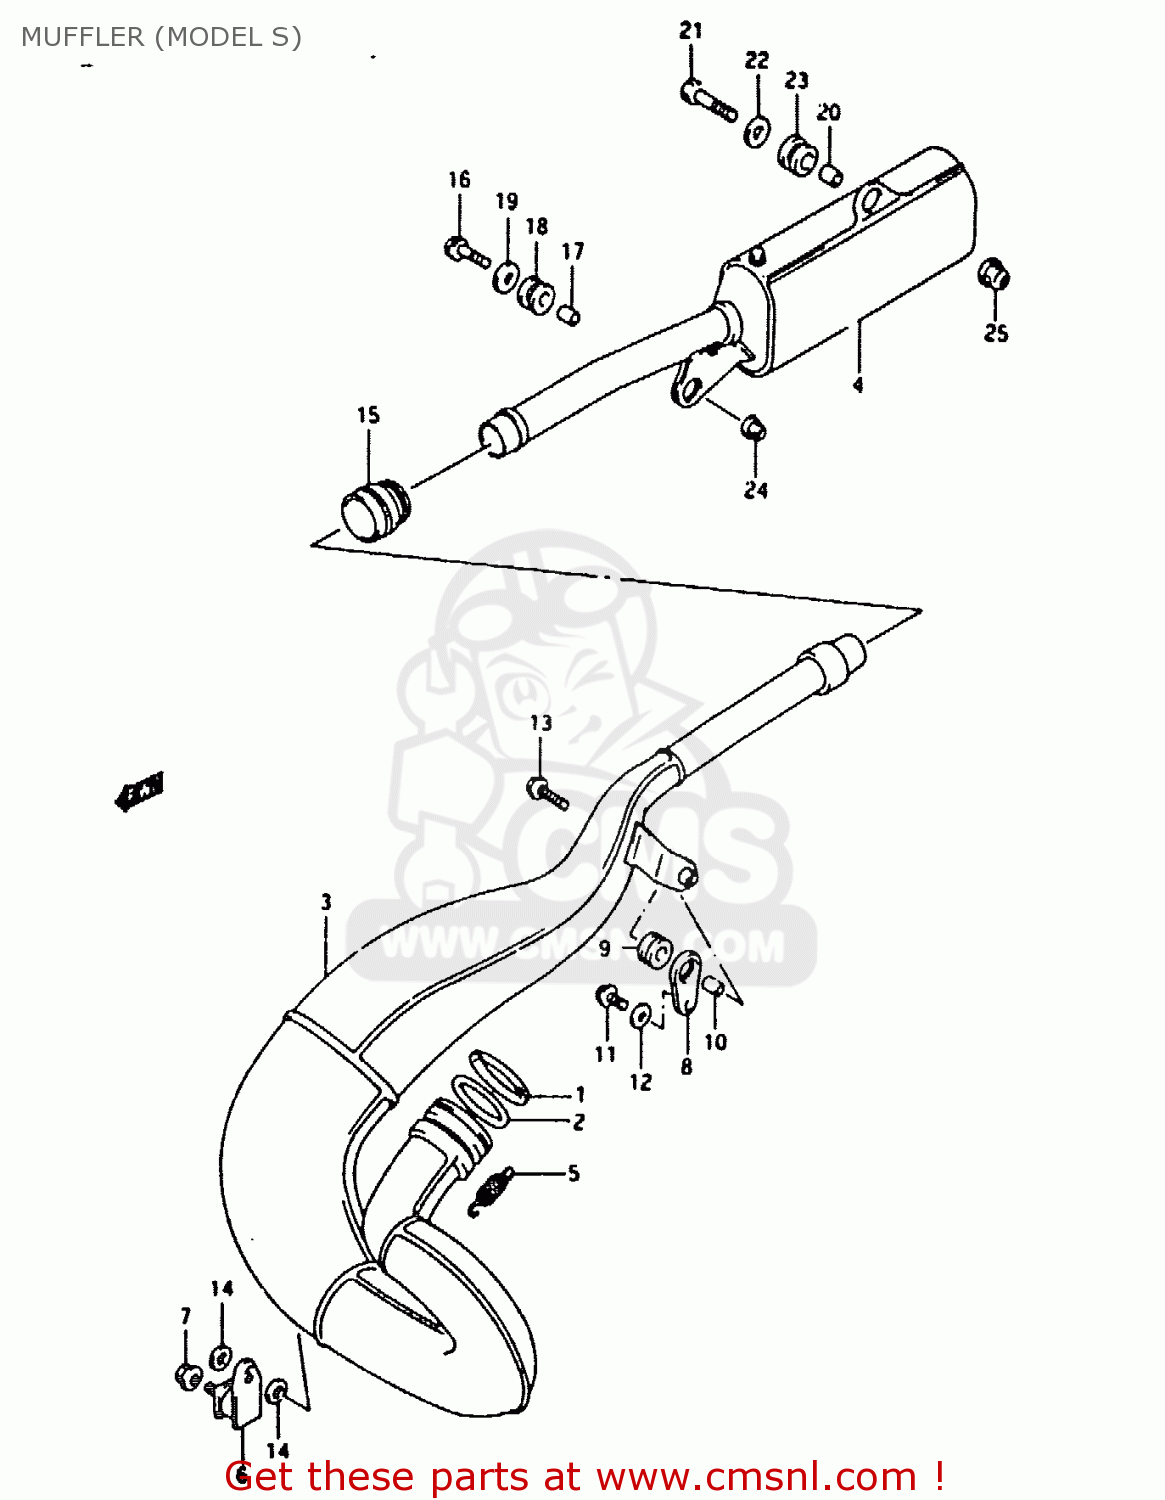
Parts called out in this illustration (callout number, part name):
1	WASHER,EXHAUST PIPE
2	O RING,EXHAUST PIPE
3	BODY,MUFFLER,FIRST
4	MUFFLER, 2ND
5	SPRING
6	DAMPER,MUFFLER SUPPORT
7	NUT
8	PLATE,MUFFLER MTG
9	CUSHION,MUFFLER
10	SPACER (6.4X9X13.5)
11	BOLT
12	WASHER (6.5X20X1.2)
13	SCREW
14	WASHER (8.5X19X2.3)
15	CONNECTOR,MUFFLER
16	SCREW
17	SPACER (6.8X10X9)
18	CUSHION
19	WASHER (6.5X29X1.6)
20	SPACER(8.1X11.5X13)
21	BOLT
22	WASHER (8.5X29X1.6)
23	CUSHION
24	NUT
25	NUT
